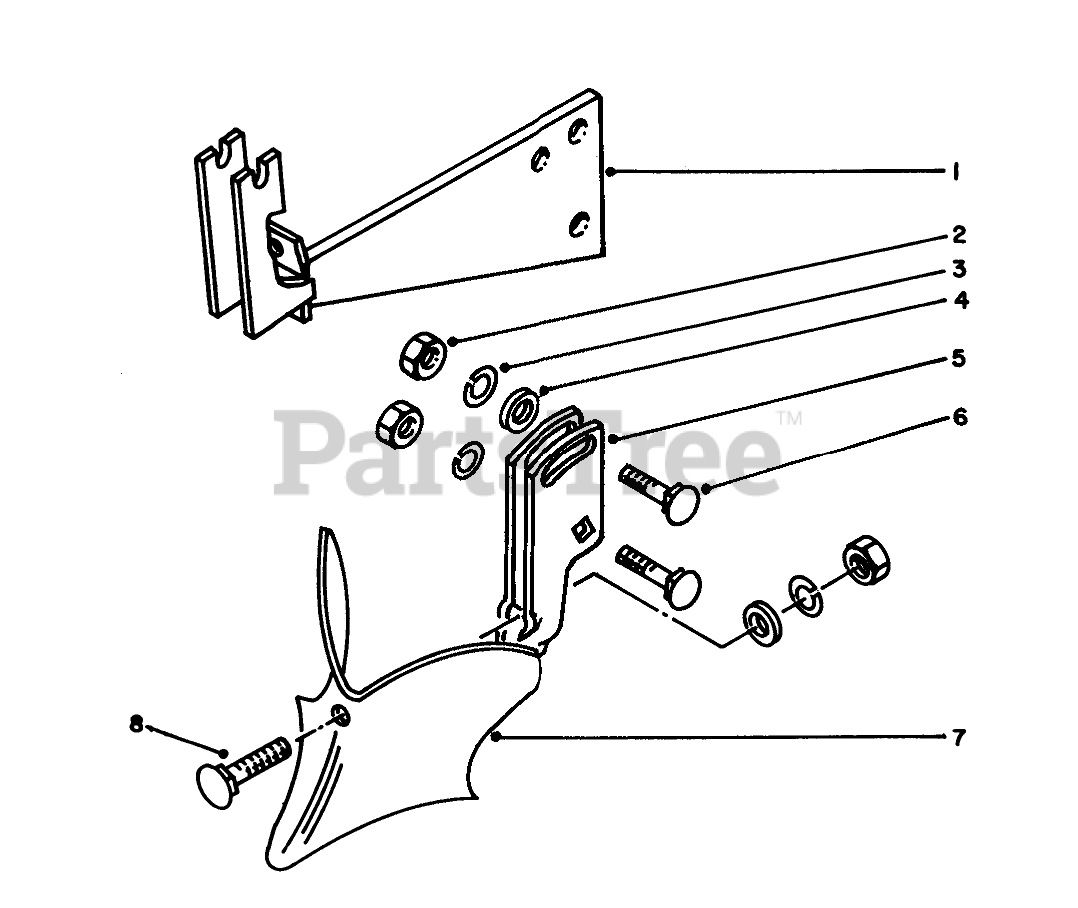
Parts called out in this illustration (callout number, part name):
1	Support
2	NUT-HEX
3	WASHER-LOCK
4	WASHER-FLAT
5	Holder
6	BOLT-CARR
7	Shovel
8	Plow Bolt
